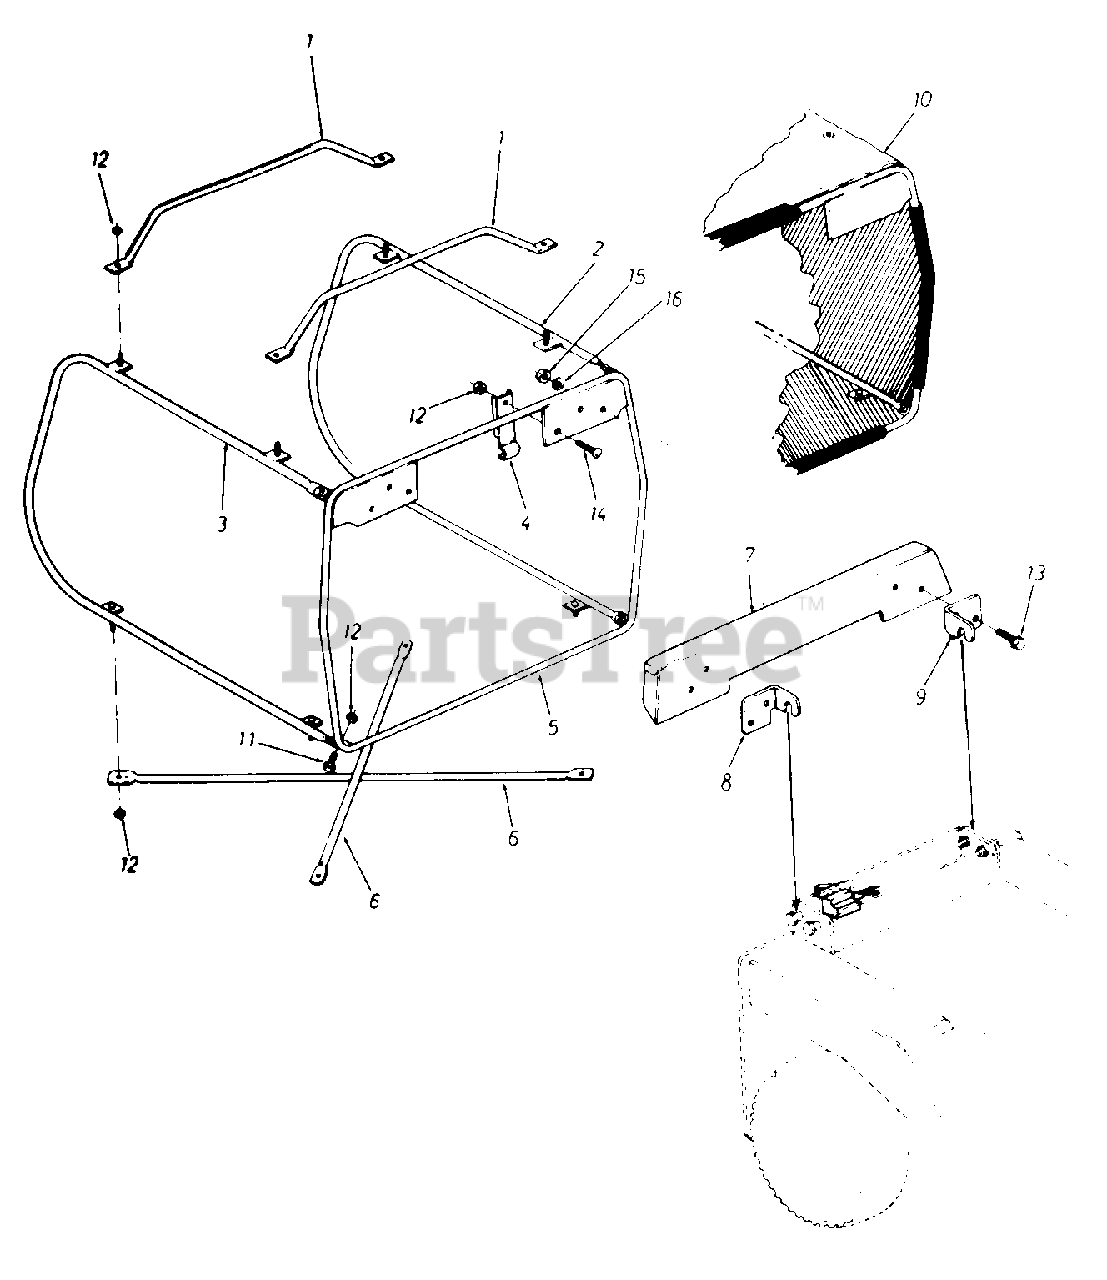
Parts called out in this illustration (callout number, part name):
1	Catcher Handles
2	Catcher Side Frame Ass'y. L.H.
3	Catcher Side Frame Ass'y. R.H.
4	Switch Actuator Bracket
5	Catcher Frame Ass'y.
6	Bottom Cross Brace
7	Dust Cover
8	Hinge-R.H.
9	Hinge-L.H.
10	Grass Bag
11	Hex Scr. 1/4-20 x .62" Lg.*
12	Hex Cent. L-Nut 1/4-20 Thd.
13	Hex Sems Scr. 5/16-18 x 1.00" Lg.*
14	Carriage Bolt 1/4-20 x .62" Lg.*
15	Hex Nut 5/16-18 Thd.*
16	L-Wash. 5/16" Scr.*
